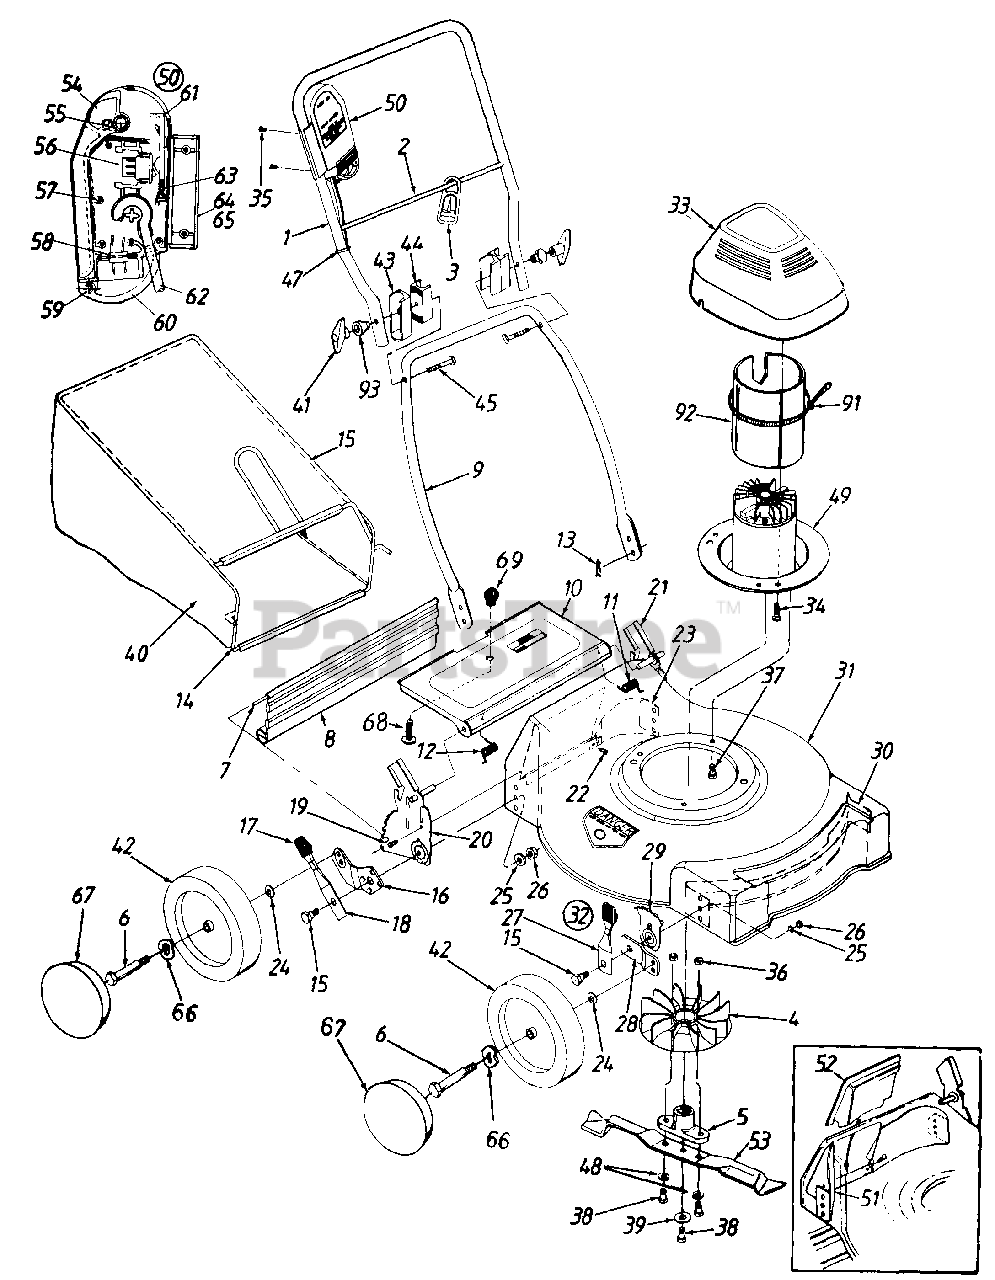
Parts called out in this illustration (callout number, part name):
1	Upper Handle
2	Cord Control Rod
3	Strain Relief - Cord
5	Blade Adapter
7	Rear Flap Wire
12	Door Spring - R.H.
13	Hairpin Clip
16	Pivot Bar - R.H.
17	Spring Lever Knob
19	Hex AB-Tap Scr. 1/4 x .62" Lg.
22	Torx . Mach. AB-Tap Scr. 1/4 x .62" Lg.
25	Bell-Wash. .39" I.D. x 1.38" O.D.
26	Hex Nut 3/8-16 Thd.
27	Spring Lever Ass'y. w/Knob
29	Height Adj. Plate
33	Motor Cover
34	Scr. #10-16 x .75" Lg.
35	Self-Tap. Scr. #7 x 1" Lg.
36	Hex Nut 3/8-24 Thd.
37	Hex TT-Tap Scr. 3/8-16 x .75" Lg.
38	Hex Bolt 3/8-24 x 1.25" Lg.
39	Bell-Wash. .396" I.D. x 1.14"
41	Plastic Knob
42	Wheel Ass'y. Comp.
43	Upper Handle Insulator
44	Lower Handle Insulator
45	Carriage Bolt 5/16-18 x 3.25"
48	Bell-Wash. 3/8" I.D.
49	Motor, Cord & Switch Ass'y.
50	Cord & Switch Ass'y. Comp.
53	19" Mulching Blade
54	Handle - Switch Actuator
55	Spring - Switch Handle
56	Switch
57	Screw #6-32 x .5" Lg.
58	Plug Ass'y.
59	Retainer Plug Spring
60	Retainer Plug
62	Cord Ass'y.
63	Spring Latch
64	Housing - Upper Half
66	Wave Wash. .51" I.D.
67	Hub Cap
68	Truss Scr. #10-24 x .38" Lg.
91	Cable Tie
92	Insulator Motor Hsg.
93	Insulator - Knob
